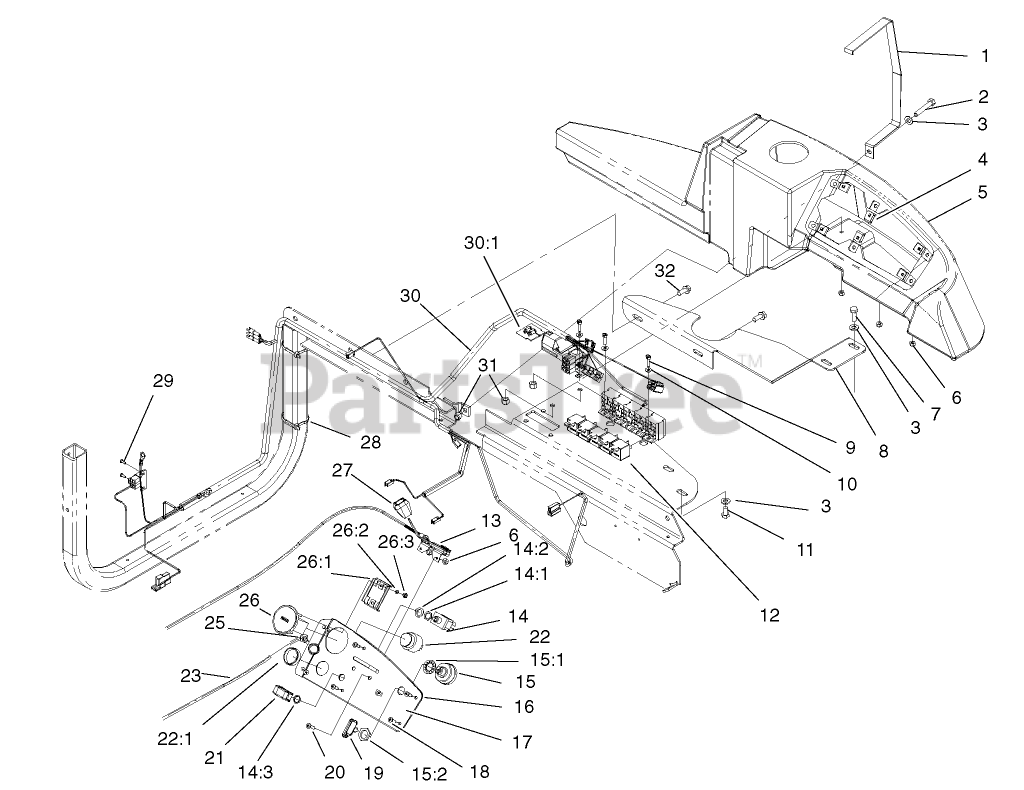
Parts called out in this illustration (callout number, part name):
1	STRAP-CONSOLE
2	SCREW-HH
3	WASHER-PLAIN
4	CLIP-TINNERMAN
5	CONSOLE
6	NUT-LOCK, NI
7	SCREW-HH
8	PLATE-SUPPORT, CONSOLE
9	SCREW-HWH
10	WASHER-FLAT
11	SCREW-HH
12	RELAY
13	THROTTLE CONTROL ASM
14	SWITCH-TOGGLE, SEALED
14:1	NUT-HEX, SPECIAL
14:2	TAB-WASHER
15	IGNITION SWITCH ASM
15:1	WASHER-LOCK
16	PANEL - INSTRUMENT
17	DECAL - INSTRUMENT
18	SCREW-PPH
19	KEY-IGNITION
20	SCREW-PPH
21	COVER-PTO SWITCH
22	AUDIO ALARM ASM
22:1	NUT-PLASTIC, KNURLED
23	CONTROL-CHOKE
25	NUT-HJ
26	Hourmeter
26:1	CLAMP-HOUR METER
26:2	WASHER-LOCK
26:3	NUT-HEX
28	TIE-CABLE
29	SCREW-TAP
30	HARNESS
30:1	DIODE-BOARD, CIRCUIT
31	NUT-LOCK, NI
32	SCREW-HWHTF
